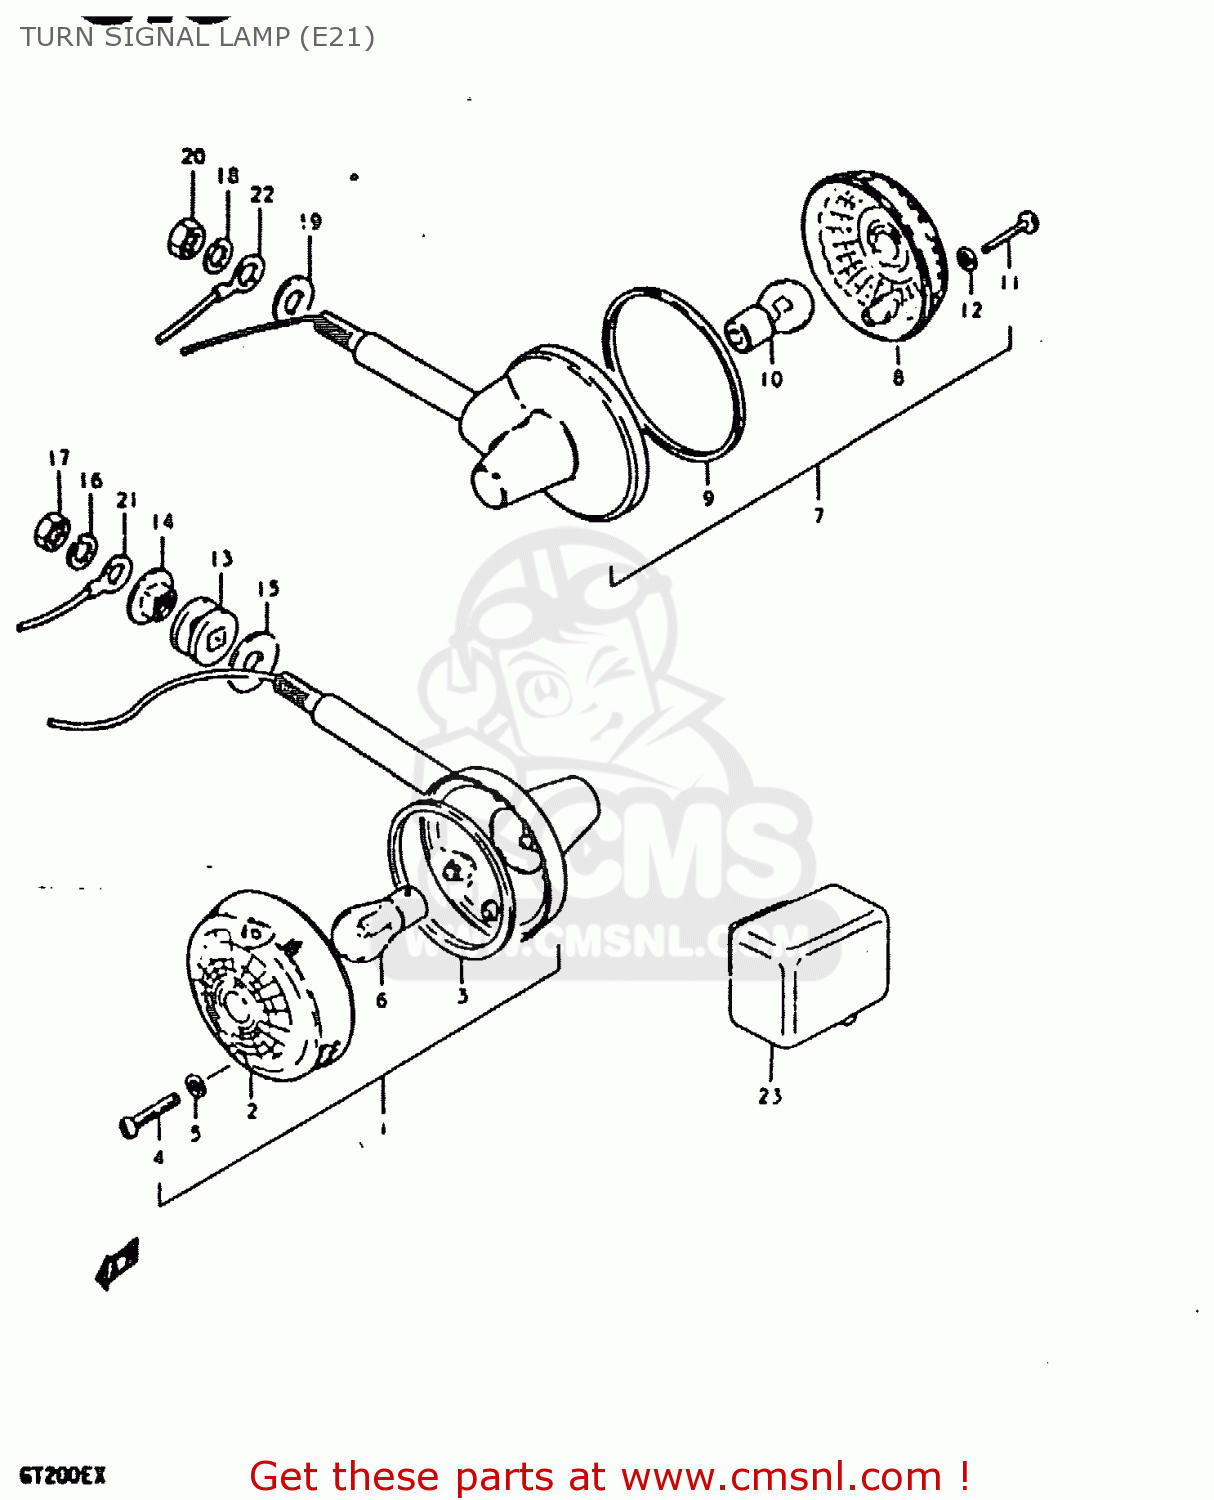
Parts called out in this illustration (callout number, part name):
1	LAMP ASSEMBLY,FRONT TURN SIGNAL
2	LENS
3	GASKET (NAS)
4	SCREW
5	GASKET (NAS)
6	BULB 12V 21W
7	LAMP, REAR TURN SIGNAL
8	LENS
9	GASKET (NAS)
10	BULB 12V 21W
11	SCREW
12	GASKET (NAS)
13	CUSHION
14	SPACER,RR TURNSIGNAL LAMP
15	WASHER
16	LOCK WASHER
17	NUT
18	LOCK WASHER
19	WASHER
20	NUT
21	LEAD WIRE,EARTH
22	LEAD WIRE, EARTH
23	RELAY,TURN SIGNAL
